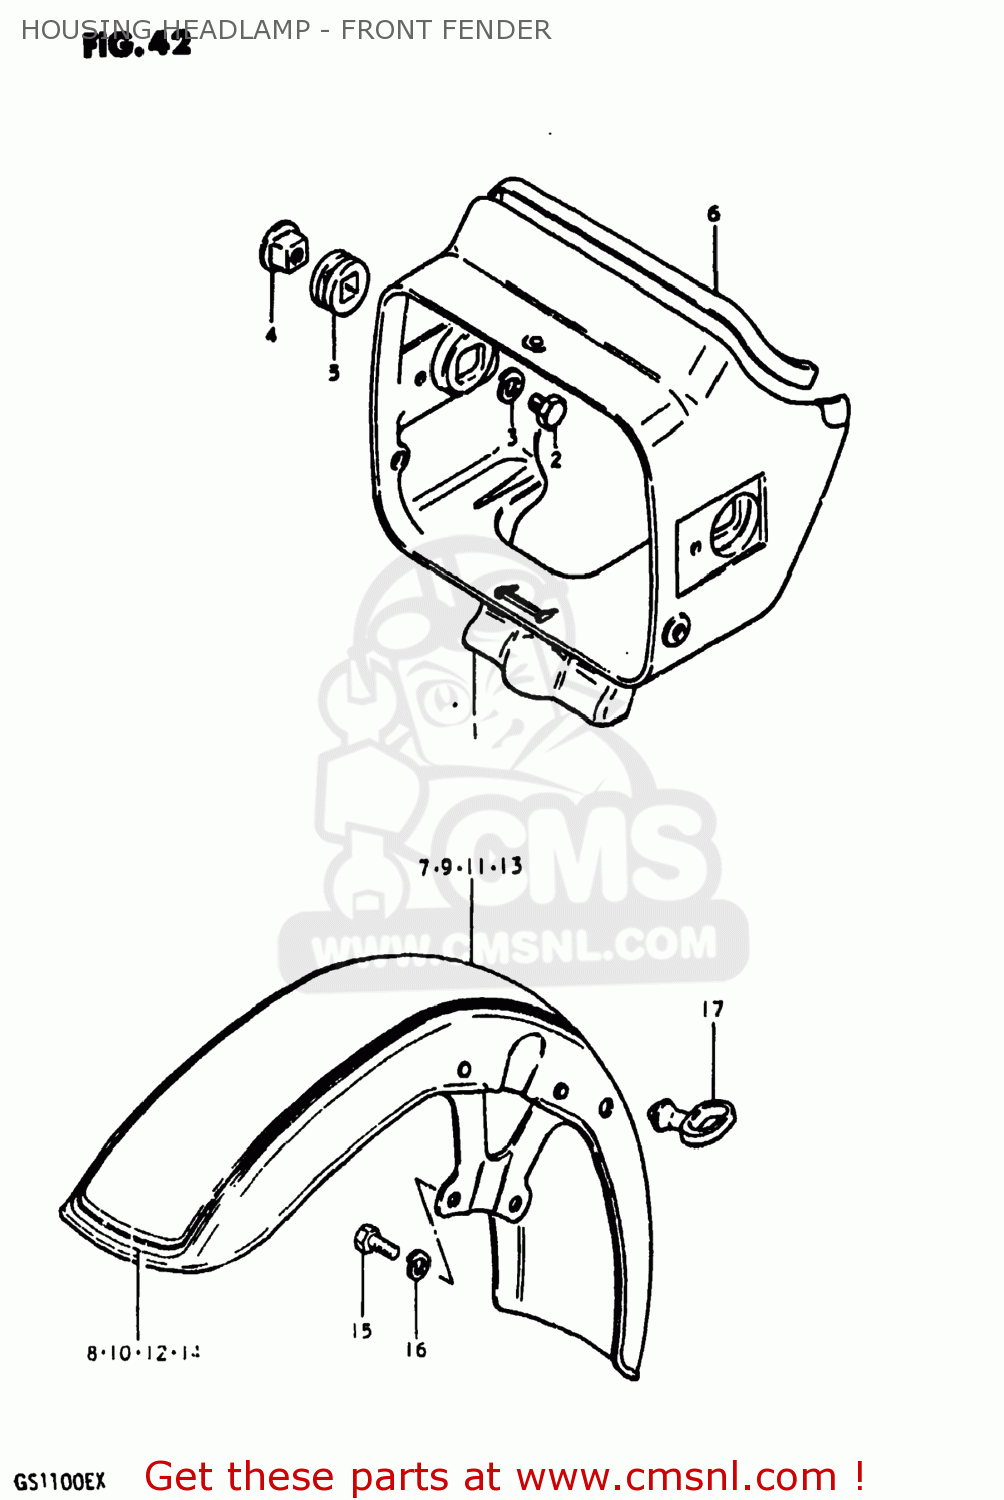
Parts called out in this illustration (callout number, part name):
1	HOUSING,HEADLAMP
2	BOLT
3	LOCK WASHER
4	SPACER,HEADLAMP HOUSING
5	CUSHION,HEADLAMP HOUSING
6	FENDER,FRONT
7	FENDER,FRONT
8	TAPE,FRONT FENDER
9	FENDER,FRONT
10	TAPE,FRONT FENDER
11	FENDER,FRONT
12	TAPE,FRONT FENDER
13	FENDER,FRONT
14	TAPE,FRONT FENDER
15	BOLT
16	LOCK WASHER
17	GUIDE,CABLE
